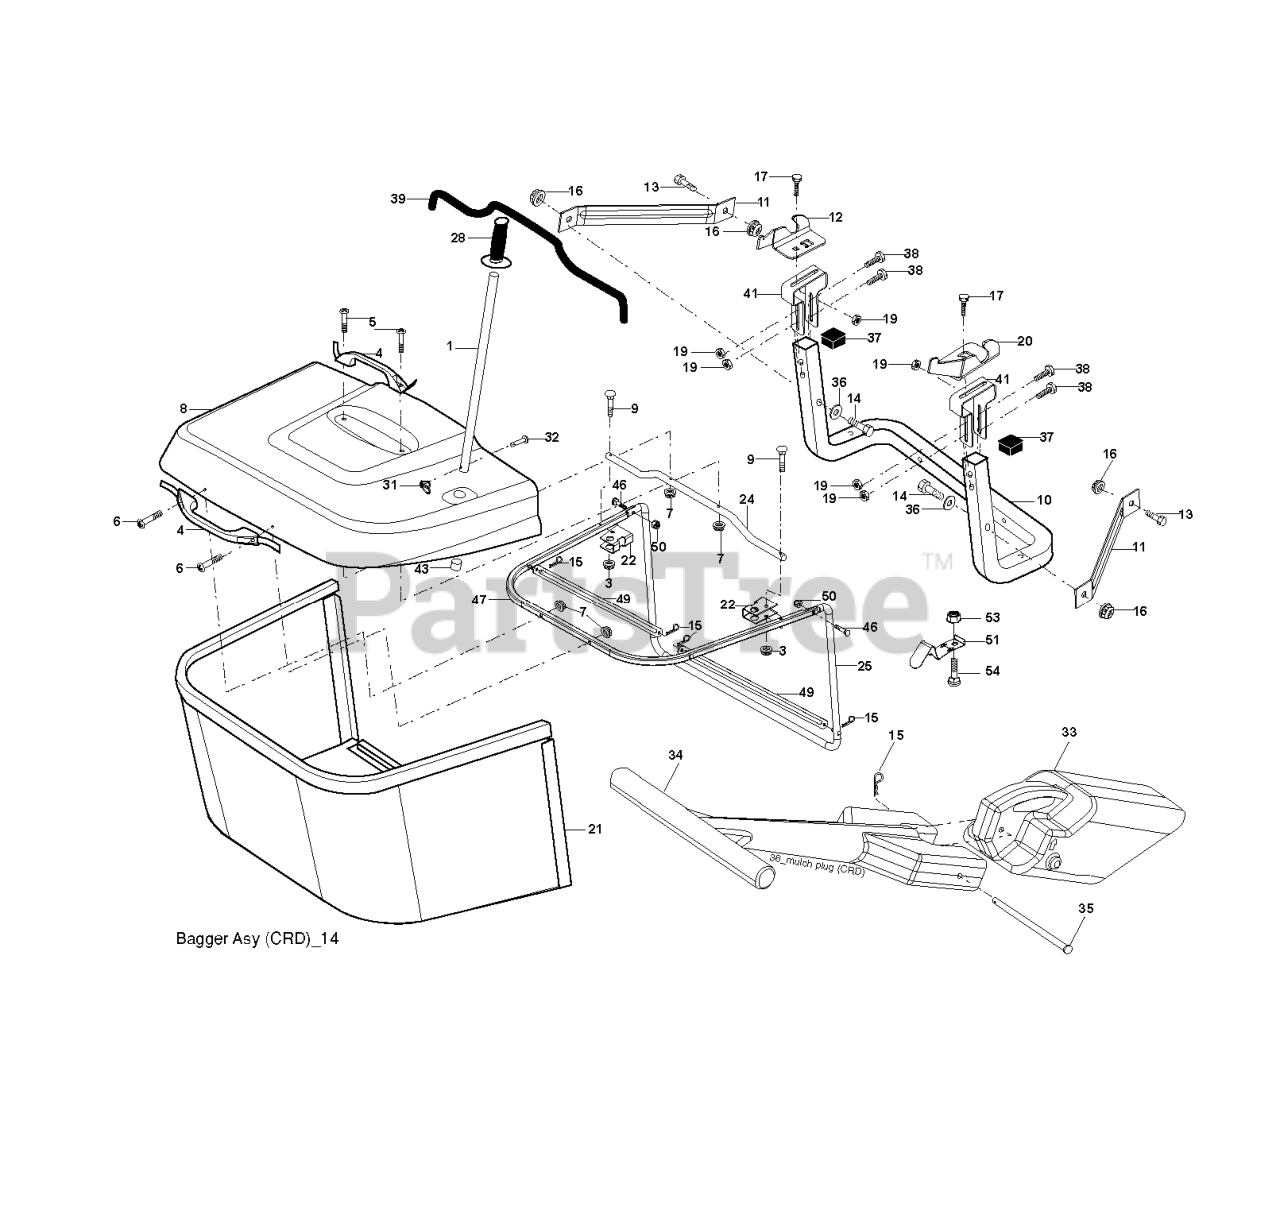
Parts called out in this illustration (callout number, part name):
1	TUBE HANDLE
3	NUT T
4	HANDLE.BAGGER.W/LVRS.BLK.CRD
5	SCREW.PAN.HEAD
6	REPL BY 532 75 00-29
8	COVER.PNT.BGR.CRD.WSLOTS.MS668
9	Bolt Carriage 1/4-20 x 2.25d x Gr.5
10	TUBE
11	BRACKET.SUPPORT.UPPER.BAG.CRD
12	BRKT PIVOT
14	BOLT-HEX EAK
15	RETAINER-SPRNG RB
16	NUT LOCK FLG 3/8-16 UNC
17	RP BOLT 5/16-18 X3/4 ZN/YEL GR
19	NUT LOCK HEX FLANGE 5/16-18
20	BRKT.PIVOT.RH.CRD
21	BAGGER.ASM.CRD.2007
22	BRKT.SIDE.BAG.CRD
24	TUBE.PIVOT.BAG.CRD.BLACK
25	PIPE
28	GRIP.HANDLE.BLACK
31	RETAINER CLIP
32	RIVET,DRILLED
33	MULCH PLUG, CTH150
34	HANDLE.MULCHER.92.CRD (2 2)
36	WASHER
37	Plug Support Bagger CRD
38	BOLT.5/16-18X2.5
39	SEAL.TRIM.37'
41	BRKT.VERT.ADJ.BAGGER.CRD
43	PLUG, TUBING END
46	BOLT.CARRIAGE.5/16-18
47	PIPE
49	ROD
50	NUT.71038.31-18.HEX.NYLOCK
51	LATCH
53	NUT
54	BOLT
